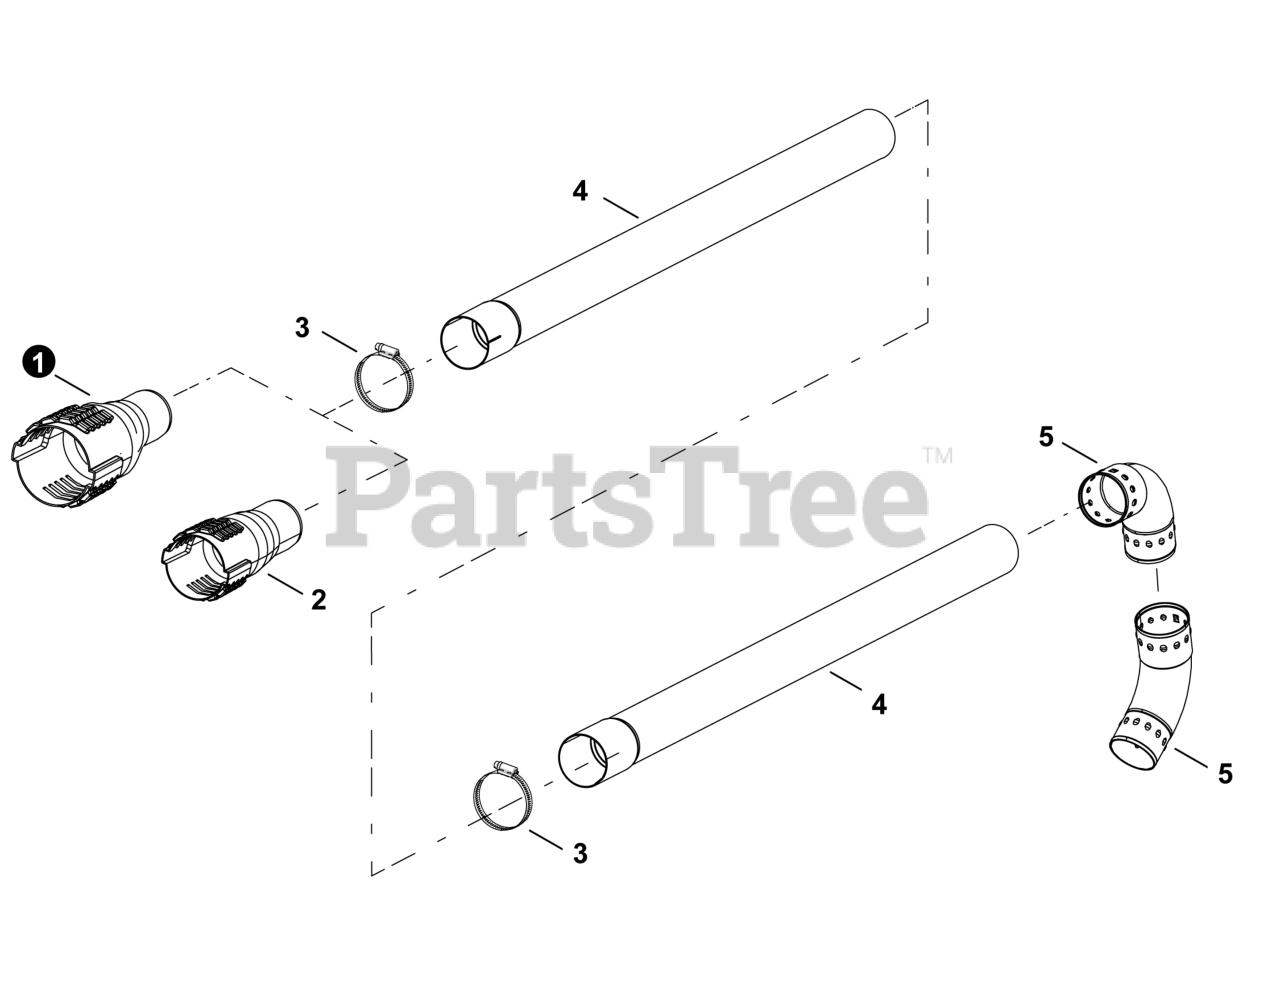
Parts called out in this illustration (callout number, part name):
1	ADAPTER - 90 mm OD
2	ADAPTER - 86 mm OD
3	CLAMP
4	TUBE, BLOWER - STRAIGHT
5	TUBE, BLOWER - ELBOW
